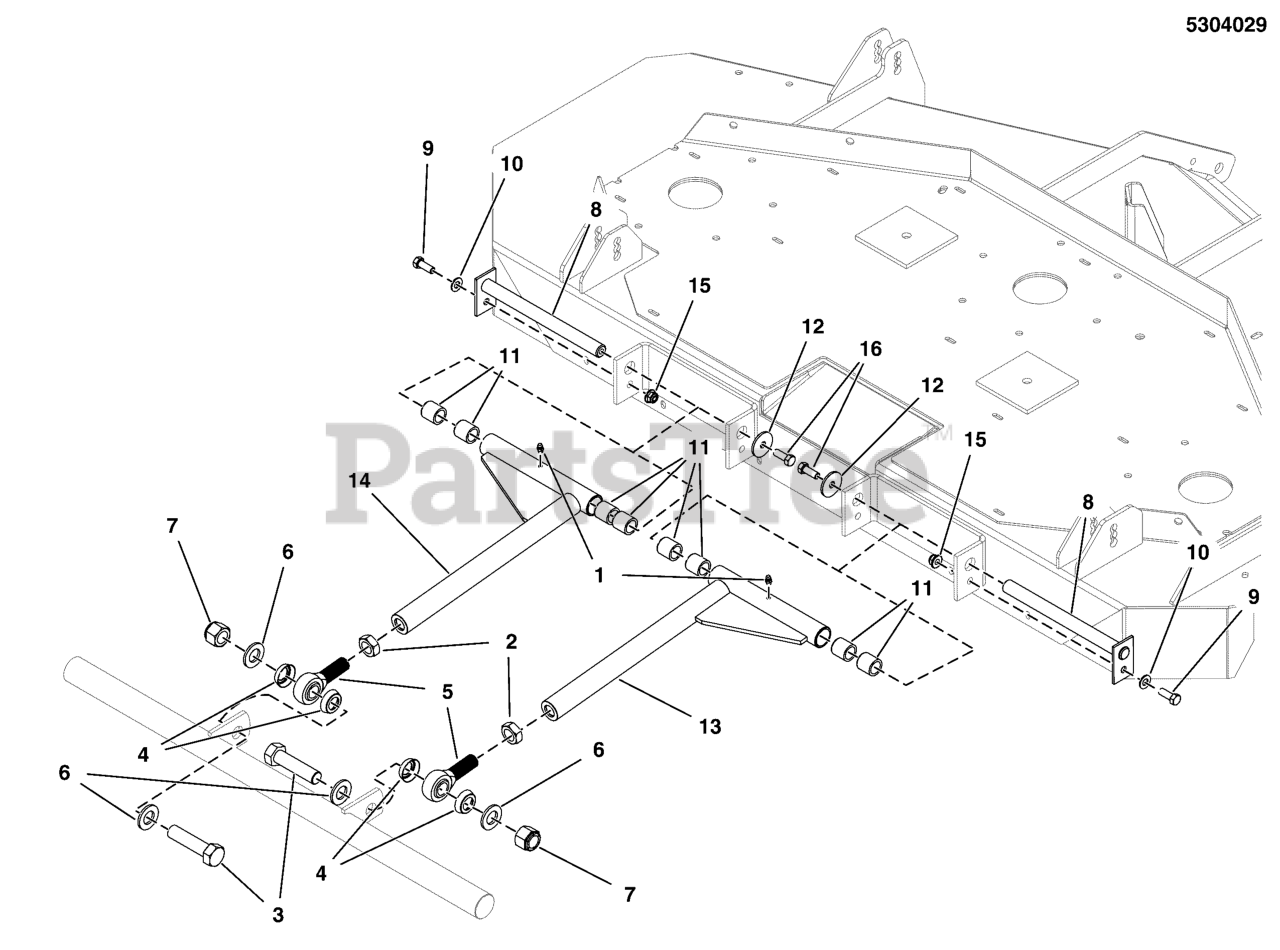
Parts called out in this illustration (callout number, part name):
1	GREASE FITTING, 1/4-28 STRAIGHT
2	NUT, 3/4-16 HEX JAM
3	BOLT-3/4-16 X 3 GD8 CZ
4	SEAL, 3/4 ROD END
5	BALL JOINT, 3/4-16, MALE
6	WASHER, 3/4 SAE
7	NUT, 3/4-16 HEX NYLON LOCK
9	BOLT, 3/8-16 X 1" GD5 CZ
10	WASHER, 3/8 SAE
11	BUSHING, .75 X 1.00 X 1.00, PLASTIC
12	WASHER, .390 X 1.50 X .109, CZ
13	WELD, PUSHER BAR, IS3200Z, RH - BLK
14	WELD, PUSHER BAR, IS3200Z, LH - BLK
15	NUT, 3/8-16 HEX NYLOCK FLANGE
16	BOLT, 3/8-16 X 3/4, PLT W/PATCH
